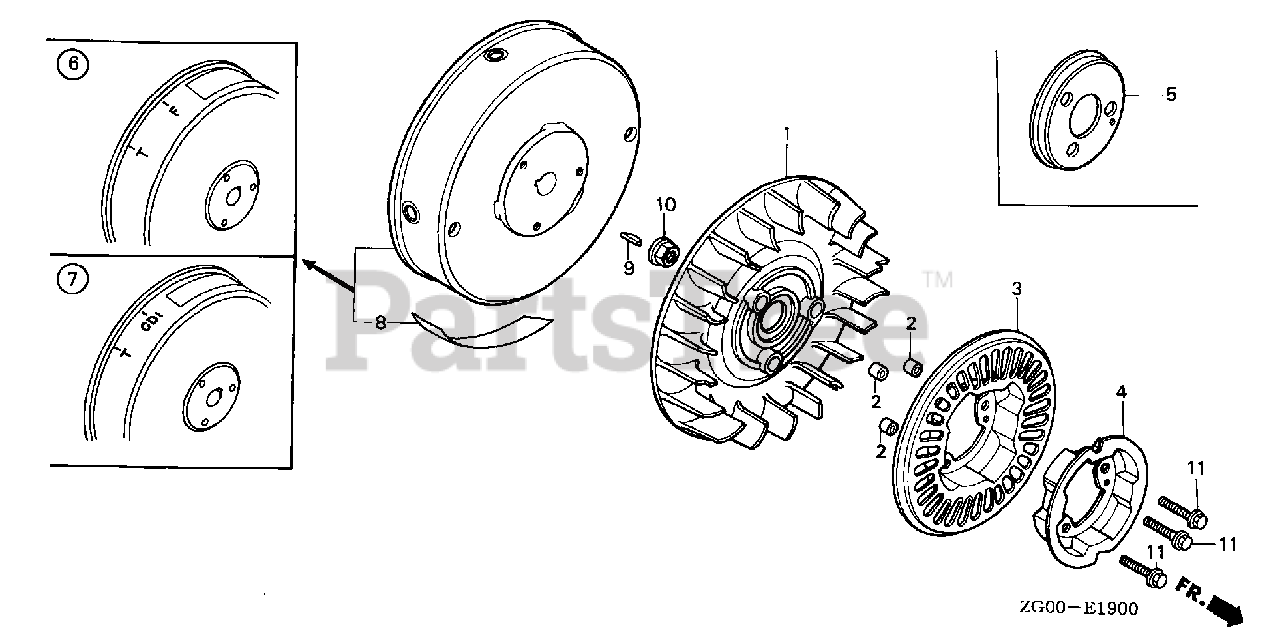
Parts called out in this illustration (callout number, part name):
1	FAN, COOLING
2	COLLAR, FAN
3	GRID, SCREEN
4	PULLEY, STARTER
8	MARK, FLYWHEEL CAUTION
9	KEY, WOODRUFF (3MM)
10	NUT, FLANGE (12MM)
11	BOLT, FLANGE (6X22)
